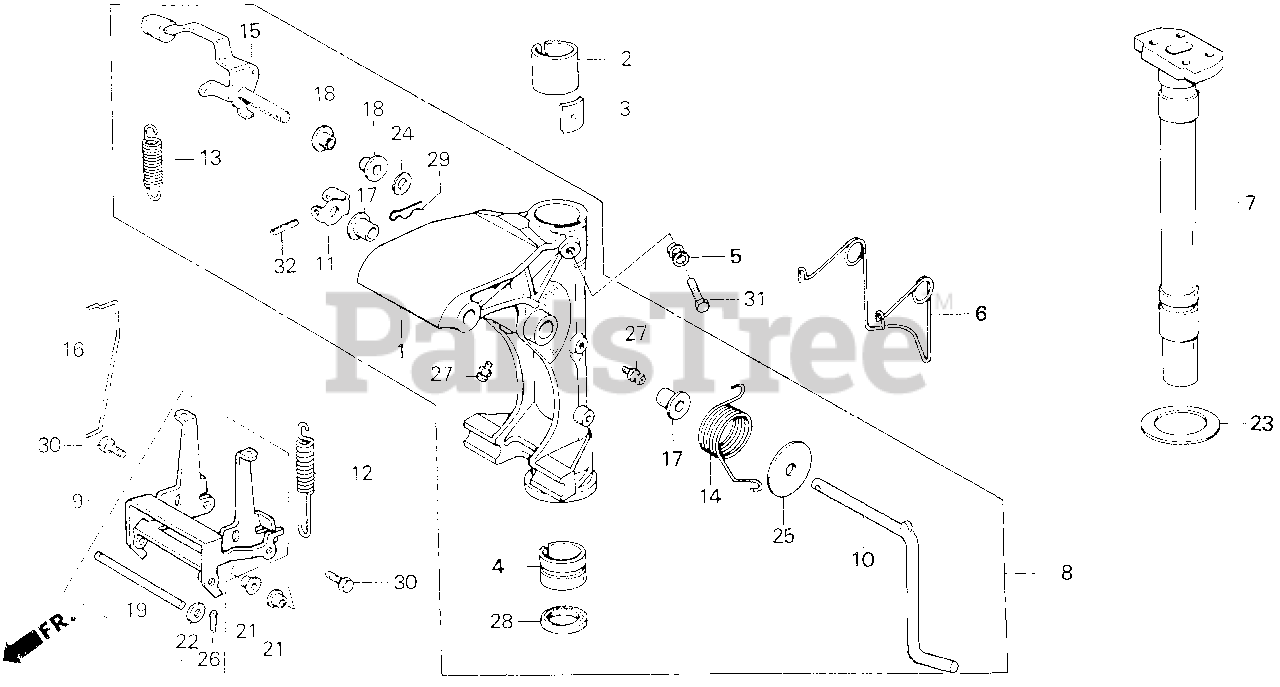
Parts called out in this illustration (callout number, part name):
1	CASE, SWIVEL *B107* (SENIOR BLUE) (NOT AVAILABLE)
2	LINER, SWIVEL CASE
3	BLOCK, FRICTION
4	BUSH, SWIVEL SHAFT
5	SPRING, FRICTION ADJUSTING
6	SPRING, HOOK RETURN
7	SHAFT, SWIVEL *B107* (SENIOR BLUE) (NOT AVAILABLE)
8	CASE, SWIVEL *B107* (SENIOR BLUE) (NOT AVAILABLE)
9	LOCK, REVERSE
10	LINK, TILT (NOT AVAILABLE)
11	BRACKET, TILT LEVER (NOT AVAILABLE)
12	SPRING, REVERSE LOCK
13	SPRING, TILT LEVER (NOT AVAILABLE)
14	SPRING, TILT LINK (NOT AVAILABLE)
15	LEVER, TILT (NOT AVAILABLE)
16	ROD, RELEASE SWIVEL CASE
17	BUSH, TILT LEVER (NOT AVAILABLE)
18	BUSH B, TILT LEVER (NOT AVAILABLE)
19	ROD, REVERSE LOCK
21	COLLAR (6MM) (NOT AVAILABLE)
22	WASHER, PLAIN (5MM)
23	WASHER, THRUST
24	WASHER, PLAIN (10MM)
25	WASHER, PLAIN (10MM)
26	PIN, COTTER (1.6MM)
27	FITTING, GREASE
28	OIL SEAL (32X37X7)
29	PIN, LOCK (10MM)
30	BOLT, HEX. (6X16)
31	BOLT, HEX. (8X20) (NOT AVAILABLE)
32	PIN, SPRING (4X25)
